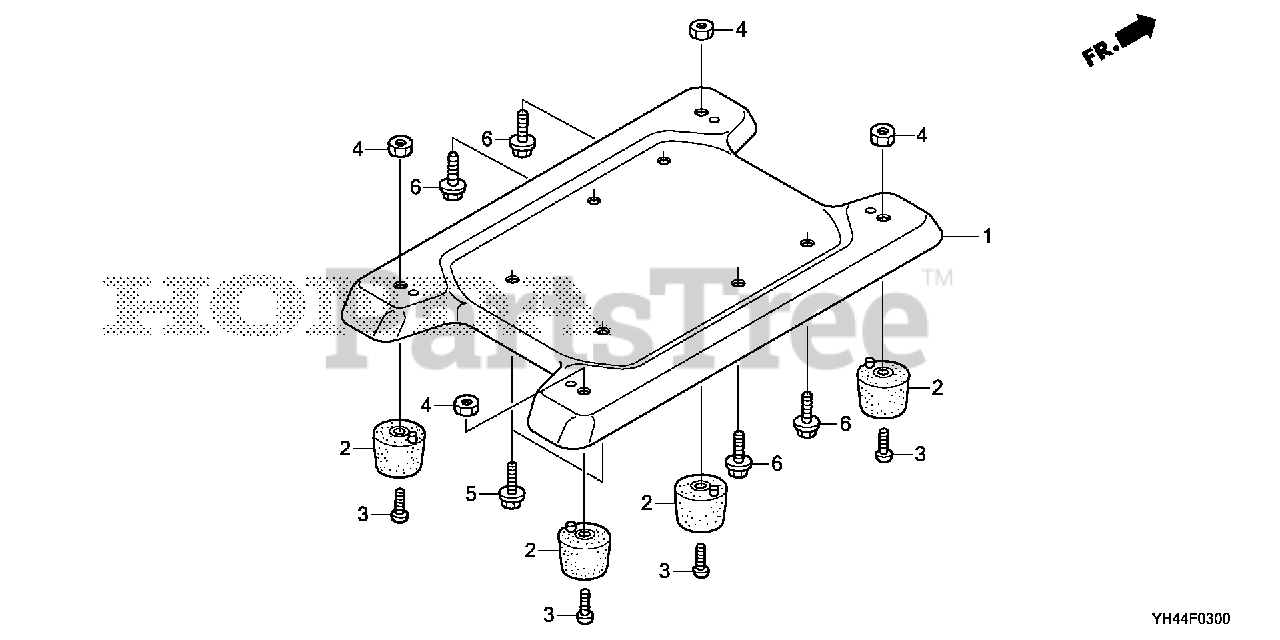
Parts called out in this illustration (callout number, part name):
1	BED, FRAME (FOR U.S.A.)
1	BED, FRAME
2	RUBBER (LOWER)
3	SCREW, PAN (6X10)
4	NUT, HEX. (6MM)
6	BOLT, FLANGE (6X14)
